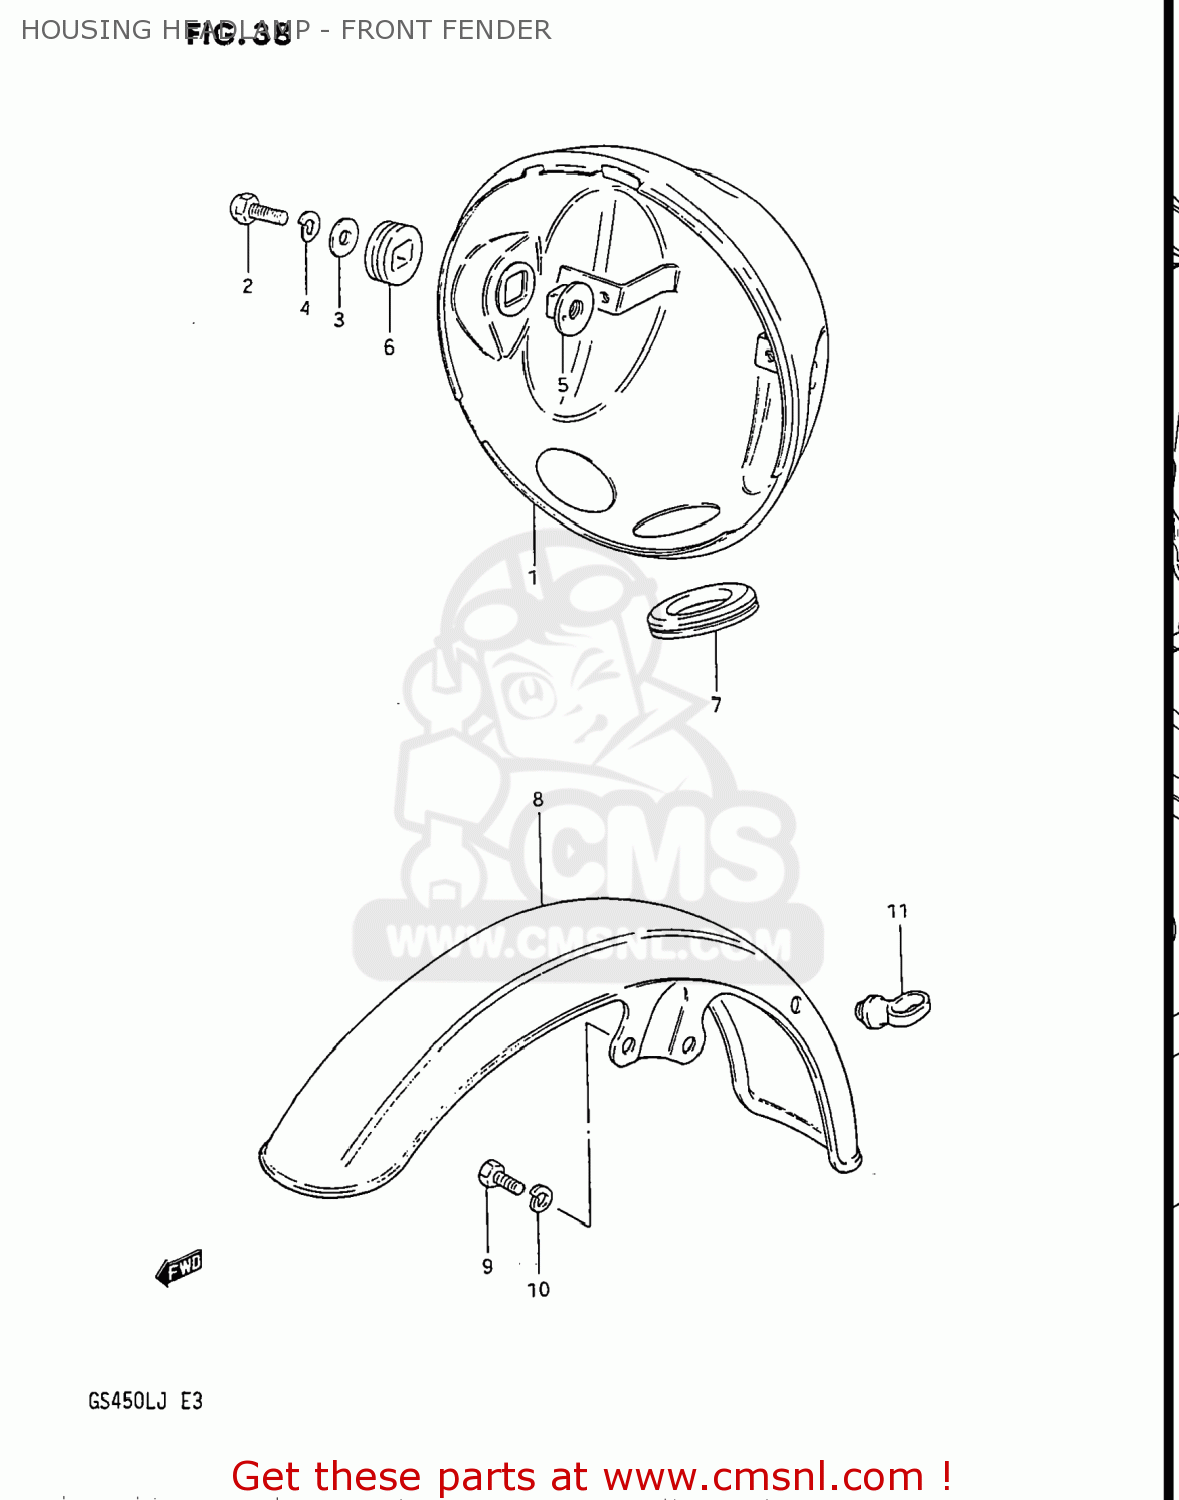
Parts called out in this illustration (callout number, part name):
1	HOUSING,HEADLAMP
2	BOLT
3	WASHER
4	LOCK WASHER
5	SPACER,HEADLAMP HOUSING
6	CUSHION,HEADLAMP HOUSING
7	GROMMET,HEADLAMP HOUSING
8	FENDER,FR
9	BOLT,8X16
10	LOCK WASHER
11	GUIDE,CABLE
